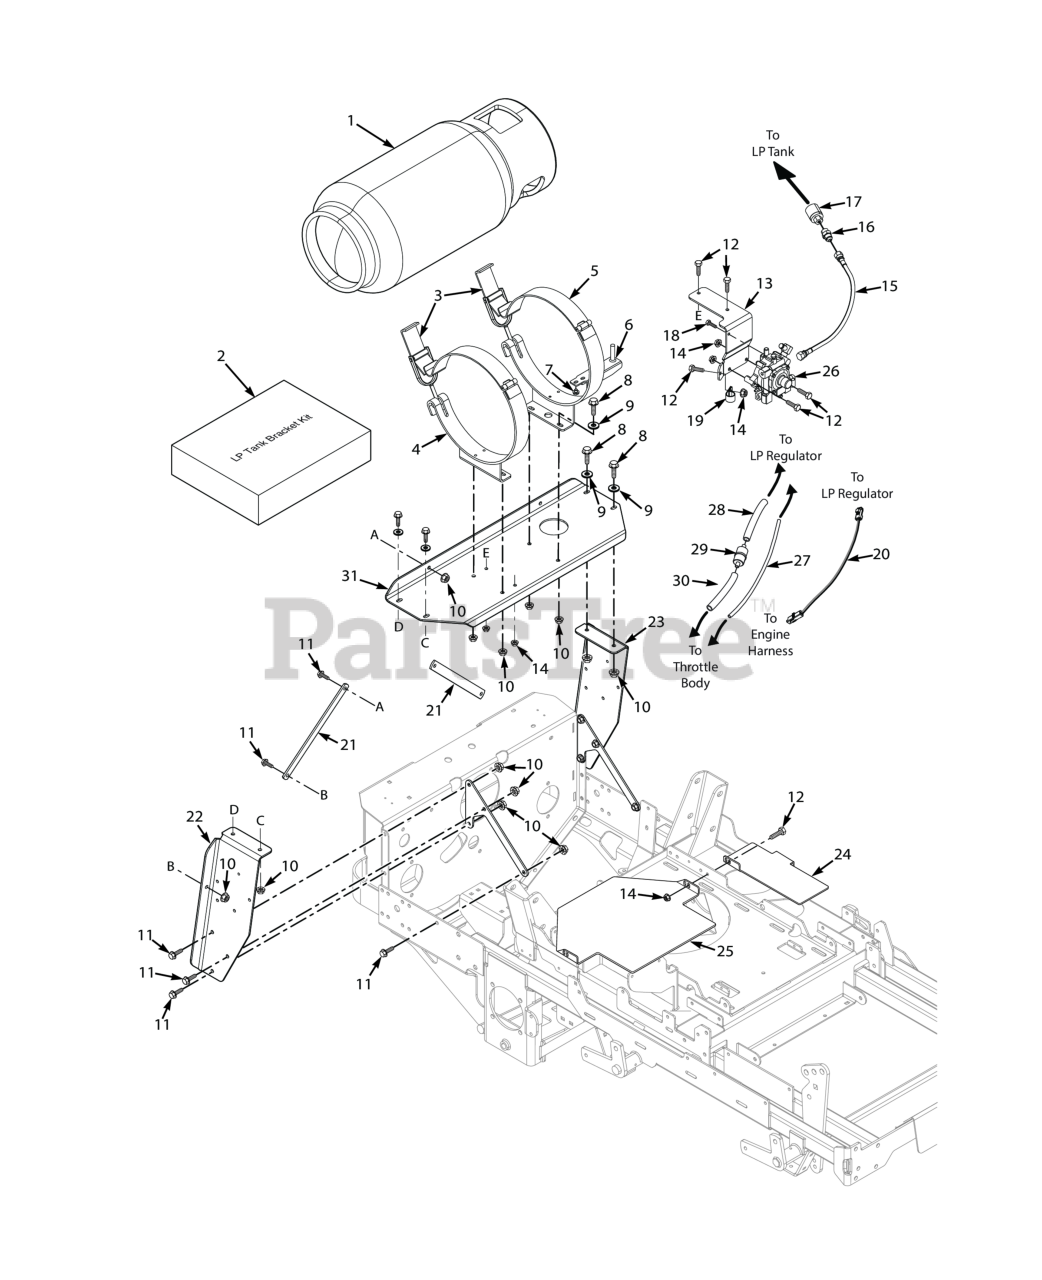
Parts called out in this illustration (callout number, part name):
1	LP Tank - Vapor
2	Mounting Bracket Kit
3	Handle, LP Tank Mounting Bracket
4	Mounting Bracket, LP Tank Rear
5	Mounting Bracket, LP Tank Front
6	LP Tank Locating Bracket
7	Bolt, Hex Head 1/2-13 x 1.5"
8	Bolt, Hex Head, 3/8-16 x 1 Gr. 5
9	Flatwasher, 3/8" Special (.391 x .938 x .105)
10	NUT, 3/8-16 SERRATED FLANGE HEX HEAD
11	Bolt, Hex Head, 3/8-16 x 3/4"
12	BOLT, SERRATED FLANGE HEX HEAD 5/16-18 X 3/4"
13	Mounting Bracket, Regulator
14	Nut, Serrated Flange 5/16-18 (Right Front Engine Mounting, Briggs and Kohler Only)
15	LP Fuel Line, 17"
16	Adapter Fitting, 9/16-18 SAE x 1/4" Pipe
17	LP Quick Coupler
18	BOLT, HEX HEAD, 1/4-20 X 3/4 GR.5
19	Clamp, Cable 3/4" ID.
20	Adapter, Wire Harness
21	Brace, Engine Mounting
22	Mounting Bracket, Tank Support - RH
23	Mounting Bracket, Tank Support - LH
24	Cover, Fuel Fill Hole
25	Cover, Fuel Tank Hole
26	LP Regulator
27	Hose
28	Hose
29	Fuel Filter
30	Hose
31	Support, LP Tank
